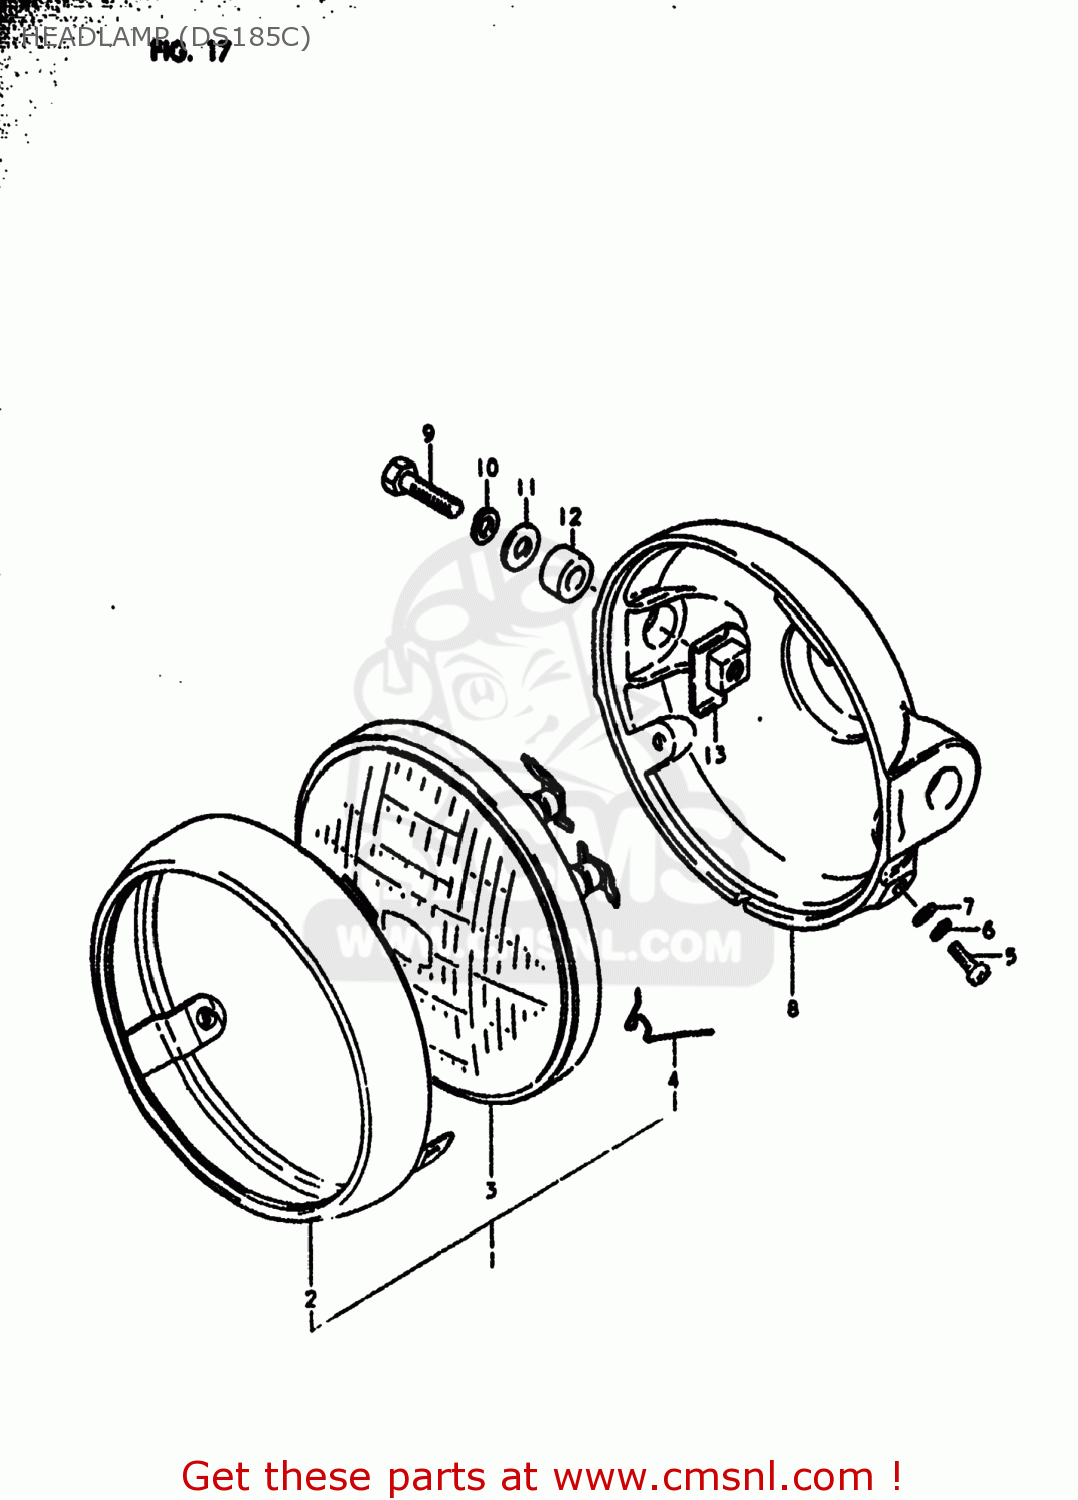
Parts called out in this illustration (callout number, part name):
1	LAMP ASSEMBLY,HEAD
2	RIM,HEADLAMP
3	LAMP UNIT
4	SPRING,HEADLAMP UNIT
5	SCREW
6	LOCK WASHER
7	WASHER
8	HOUSING,HEADLAMP
9	BOLT
10	LOCK WASHER
11	WASHER
12	SPACER (8.8X12X7)
13	PLATE,HEADLAMP HOUSING
